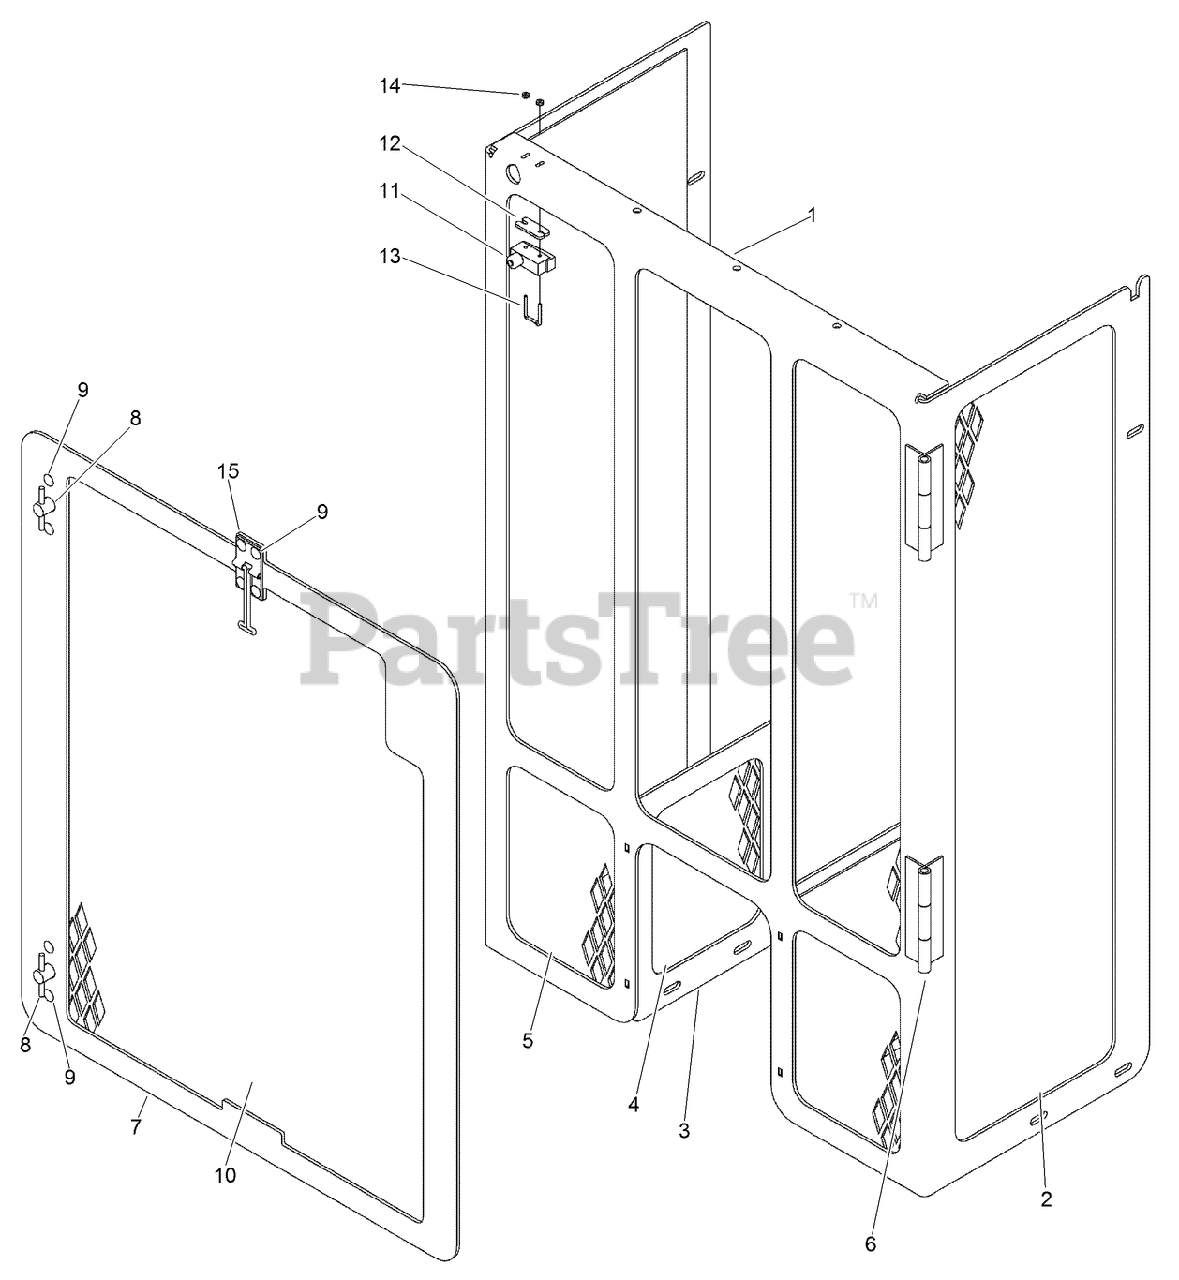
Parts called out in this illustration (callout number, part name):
1	FRAME - Stakedown Cover
2	PLATE - Guard, Expanded Metal
3	GUARD - Stakedown
4	PLATE - Guard, Expanded Metal
5	PLATE - Guard, Expanded Metal
6	HINGE - 2 Knuckle, 3/8 SS Pin, 3 Open Width
7	DOOR - Stakedown
10	PLATE - Guard, Expanded Metal
11	SWITCH-NEUTRAL START
12	SPACER-SWITCH
13	BOLT-U, SWITCH MTG (H435814)
14	NUT - KEPS Ext T Wshr #6 - 32 UNC ZP
15	LATCH-RETAINING
